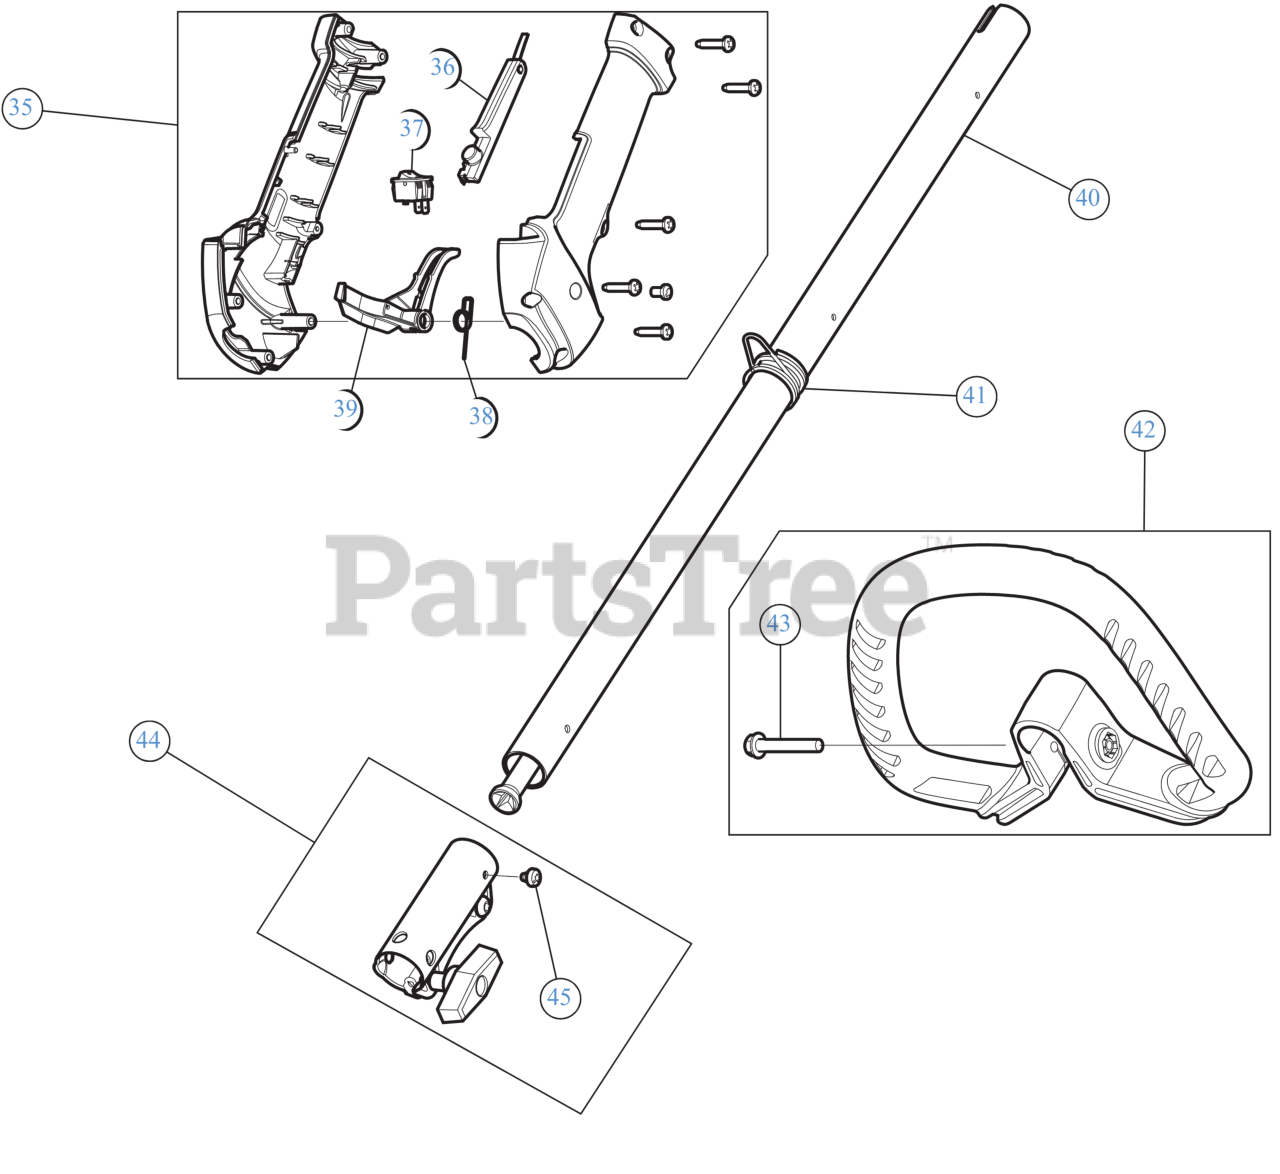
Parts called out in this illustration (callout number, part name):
35	THROTTLE GRIP ASSEMBLY
36	LEVER LOCK OUT
37	SW, MOMENTARY ON/O
38	TRIGGER SPRING
39	THROTTLE TRIGGER
40	BOOM ASSEMBLY UPR
41	CLAMP-SHOULDER STR
42	HANDLE ASSEMBLY
43	BOLT 1/4-20X1 1/2
44	SPLIT BOOM COUPLER KIT
45	SCREW, 10-32X.250 TA
